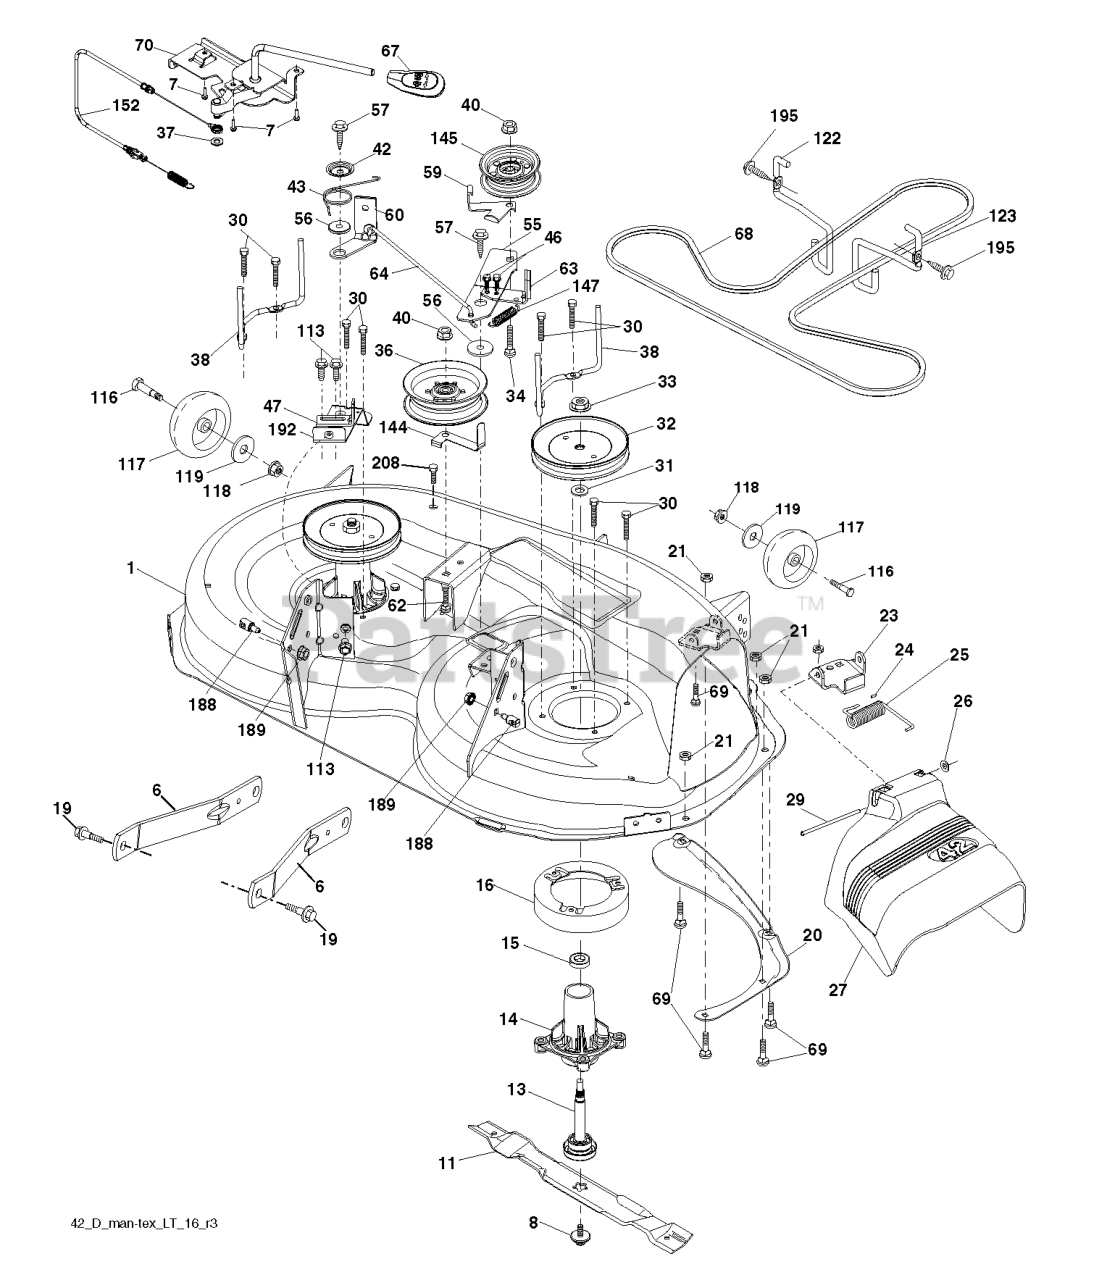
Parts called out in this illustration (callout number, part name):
1	DECK.WELDMENT.42"
6	ARM.SUSPENSION.MOWER.R
7	SCREW.#10 X 0.750.BOS
8	BOLT.WASHER.ASM.7/16-2
11	42" HI-LIFT BLADE
13	SHAFT.ASM.MDRL.N/GREASE.38
14	RP.HOUSING.MANDREL.4PT.
16	STRIPPER.MANDREL.ROUND.BLACK
19	BOLT.SHOULDER
20	BAFFLE.VORTEX
21	LOCKNUT
23	BRKT.DEFLECTOR.38"2005+
24	CAP-SLEEVE LT
25	SPRING.TORSION.DEFLECT
26	NUT PUSH M
27	SHIELD.DEFLECTOR.MOWER.42"BLAC
29	ROD.HINGE
30	SCREW, WASHER HEAD
31	WASHER.SPACER.MANDREL
32	PULLEY.MANDREL.5.438.PD
33	NUT.FLANGE.LOCK.TOP
34	BOLT.3/8-16X1.50
36	PULLEY.IDLER.2006
37	WASHER
38	KEEPER.BELT.LH.MANDREL
40	NUT LOCK FLG 3/8-16 UNC
42	SPRING.TORSION.BRAKE
43	SRPING.TORSION.RETAINE
46	SCREW.1/4-20X5/8
47	BRKT.CLUTCH.CABLE
55	IDLER.ARM
56	SPACER.RETAINER
57	SCREW 3/8-16X1
59	GUARD, BELT
60	ARM BRAKE MOWER
62	BOLT
63	ARM BRAKE MOWER
64	LINK BRAKE
67	HANDLE.CLUTCH.CABLE.LT
68	BELT.DRIVE.MOWER.TEX.42"
69	BOLT
70	CLUTCH.ASM.MANUAL.LT.PRED
113	BOLT.5/16HEX.WHS.HD
116	BOLT M
117	WHEEL.GAGE.HALF.SPOKED
118	LOCKNUT
119	WASHER.5/16.FLAT.STE.STD.
122	KEEPER BELT ENGINE LH
123	KEEPER BELT RH
144	KEEPER.BELT.MOWER
145	PULLEY.IDLER.48"PRIMARY
147	RETURN SPRING
152	CLUTCH CABLE
188	STUD.FASTNER.W/ANTI-ROTATE
189	NUT LOCK HEX FLANGE 5/16-18
192	BRKT.BRAKE.STAND.LH.
195	SCREW, 3/8-16X3/4
208	SCREW 3/8-16X1/2
